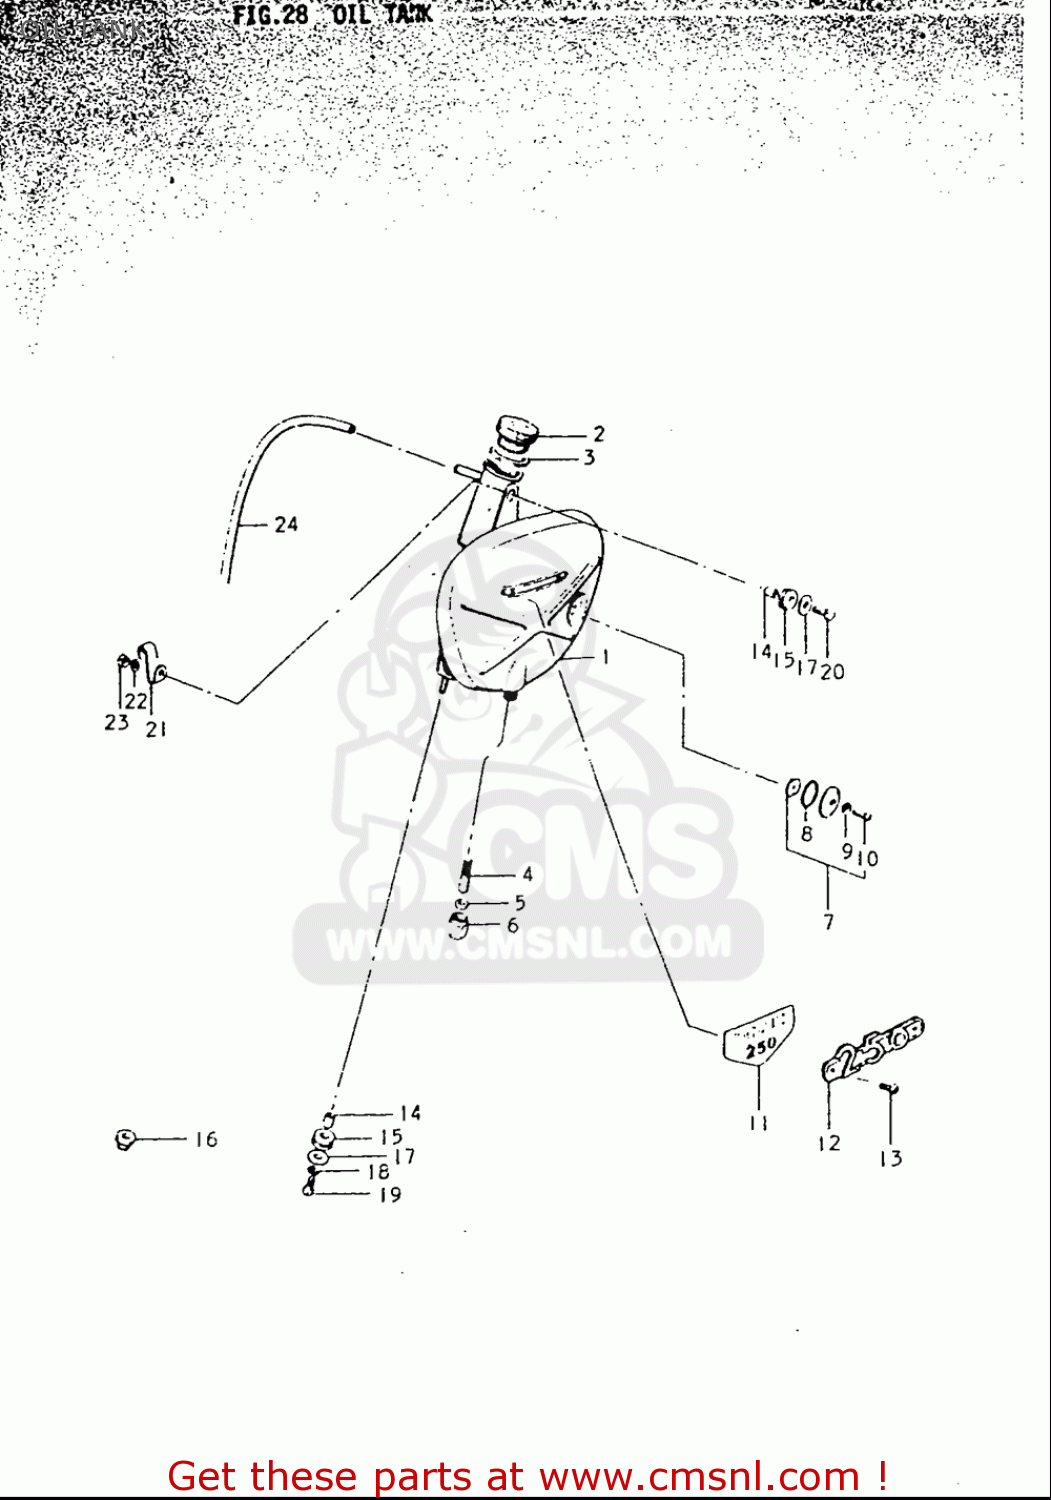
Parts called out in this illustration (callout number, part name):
2	CAP,OIL TANK
3	GASKET,OIL TANK FILLER CAP (NAS)
4	UNIT,OIL FILTER
5	GASKET,OIL OUTLET JOINT (NAS)
6	OIL OUTLET JOINT NUT
7	LENS SET,OIL INSPECTION
8	O RING(D:3,ID:23)
9	GASKET(5X9.5X1) (NAS)
10	SCREW
13	SCREW
14	SPACER,6.5X9X7
15	CUSHION
17	WASHER(6.5X20X1.2)
18	WASHER,LOCK
20	BOLT
22	WASHER,LOCK
23	NUT
